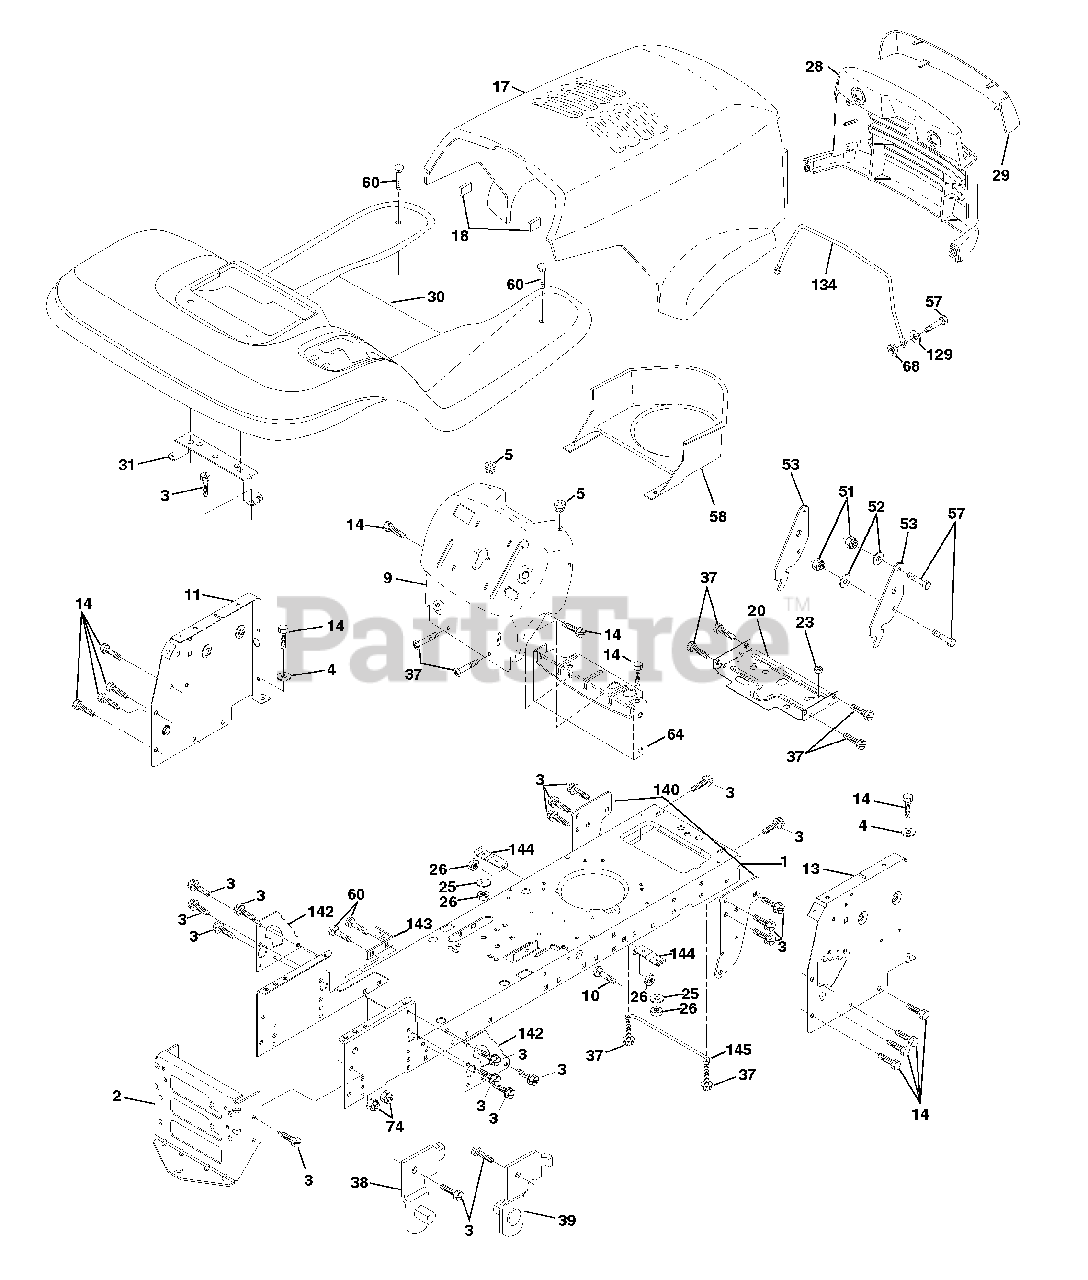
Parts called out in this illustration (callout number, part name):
1	Chassis Weldment
2	Drawbar, Stretch
3	Screw Thdrol 3/8-16x3/4 Ty-tt
4	Washer 13/32 x 3/4 x 16 Ga.
5	Bumper Hood/Dash
9	Dash P/L M, N/AMM N/HM
10	Bolt Carriage 3/8-16 x 1
11	Panel Dash Lh
13	Panel Dash Rh
14	Screw Thdrol 3/8-16x1/2 Ty-tt
17	Hood LT/PL Husqvarna
18	Bumper Hood
20	Plate Mtg Battery Fuel Tank Fr
25	Washer 13/32 X 13/16 X 12 Ga
26	Nut Lock Hex W/Ins 3/8-16 Unc
28	Grille LT/PL Husqvarna
29	Lens LT/PL Husqvarna
30	Fender Footrest STLT Pnt
31	Bracket Support Fender
37	Screw Thdrol 6/16-18 x 1/2 TYT
38	Bracket, Asm. Pivot, L.H., Mower Rear
39	Bracket, Asm. Pivot, R.H., Mower Rear
51	Nut Lock Hex W/Ins 1/4-20
52	Washer 9/32 x 7/8 x 16 Ga.
53	Bracket Pnt. Pick off LT/PL Husqvarna
57	Bolt Hex 1/4-20 x 3/4
58	Air Duct Engine P/L
60	Bolt Rdhd Sqnk 3/8-16unc x 3/4
64	Dash Lower STLT
68	Nut Keps Hex 1/4-20unc
74	Nut Crownlock 3/8-16 UNC
129	Washer 9/32 x 5/8 x 16 Ga.
134	Rod Support Hood LT/PL Husq.
140	Bracket Suspension Front
142	Plate Reinforcement STLT
143	Bracket Swaybar Chassis
144	Bracket Pnt Footrest STLT
145	Rod Pivot Chassis/Hood
